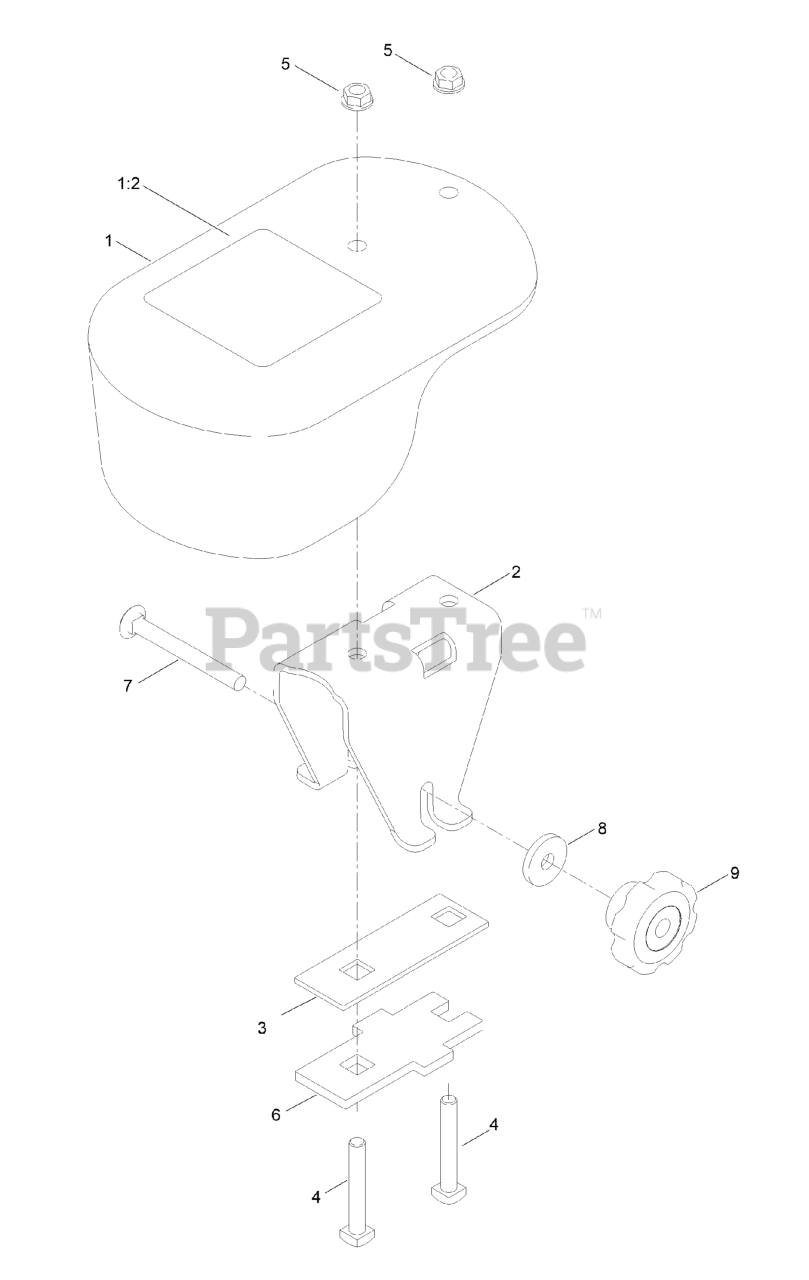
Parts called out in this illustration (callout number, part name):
1	WEIGHT WITH DECAL ASM
1:2	DECAL-WARNING, TRACTION
2	CHANNEL-MOUNT, WEIGHT
3	PLATE-BRACKET, WEIGHT
4	BOLT-SQH
5	NUT-HHF, WHIZ
6	PLATE-BRACKET, WEIGHT
7	SCREW-CARR
8	WASHER-BACKUP
